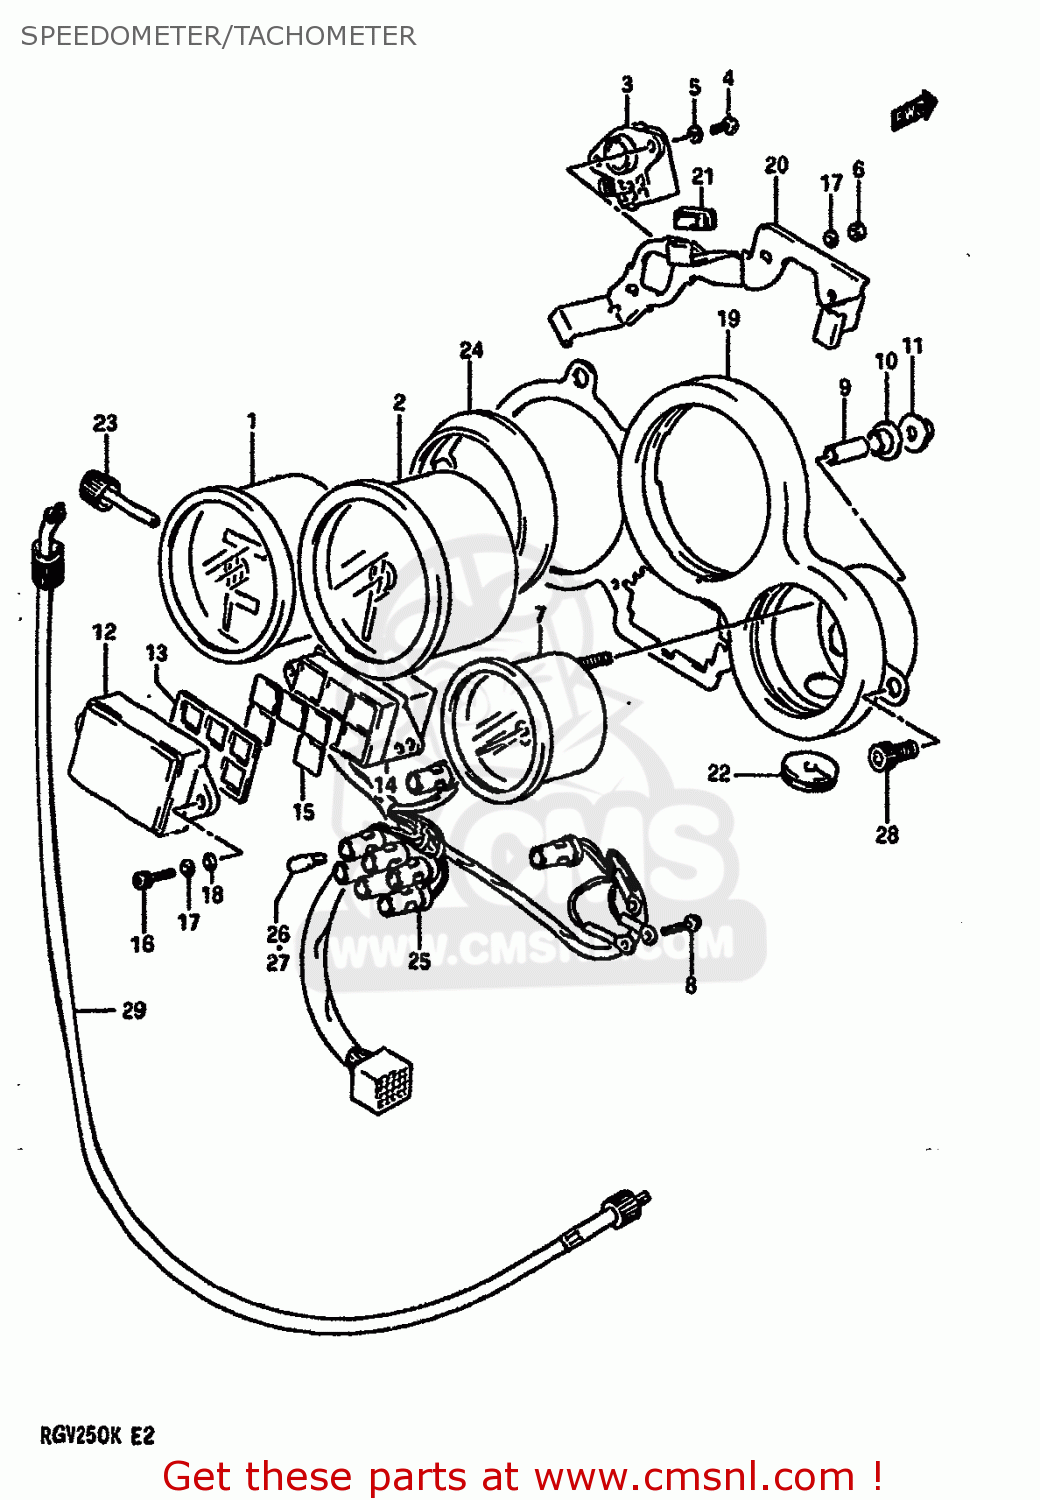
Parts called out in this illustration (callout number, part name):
1	SPEEDOMETER (KILO)
2	TACHOMETER
3	BOX,METER GEAR
4	SCREW
5	LOCK WASHER
6	NUT
7	METER, TEMPERATURE
8	SCREW
9	SPACER
10	CUSHION
11	NUT
12	LENS,PILOT LAMP
13	CUSHION
14	CASE,PILOT LAMP
15	LENS SET,PILOT LAMP
16	BOLT
17	WASHER
18	WASHER
19	BRACKET,METER
20	PLATE,SPEEDOMETER
21	CUSHION
22	GROMMET
23	KNOB,TRIP
24	CUSHION,SPEEDOMETER
25	SOCKET,SPEEDOMETER
26	BULB(12V3W,WB371,T7)
27	BULB(12V1.7W,WB372,T7)
28	BOLT
29	CABLE ASSY,SPEEDOMETER
